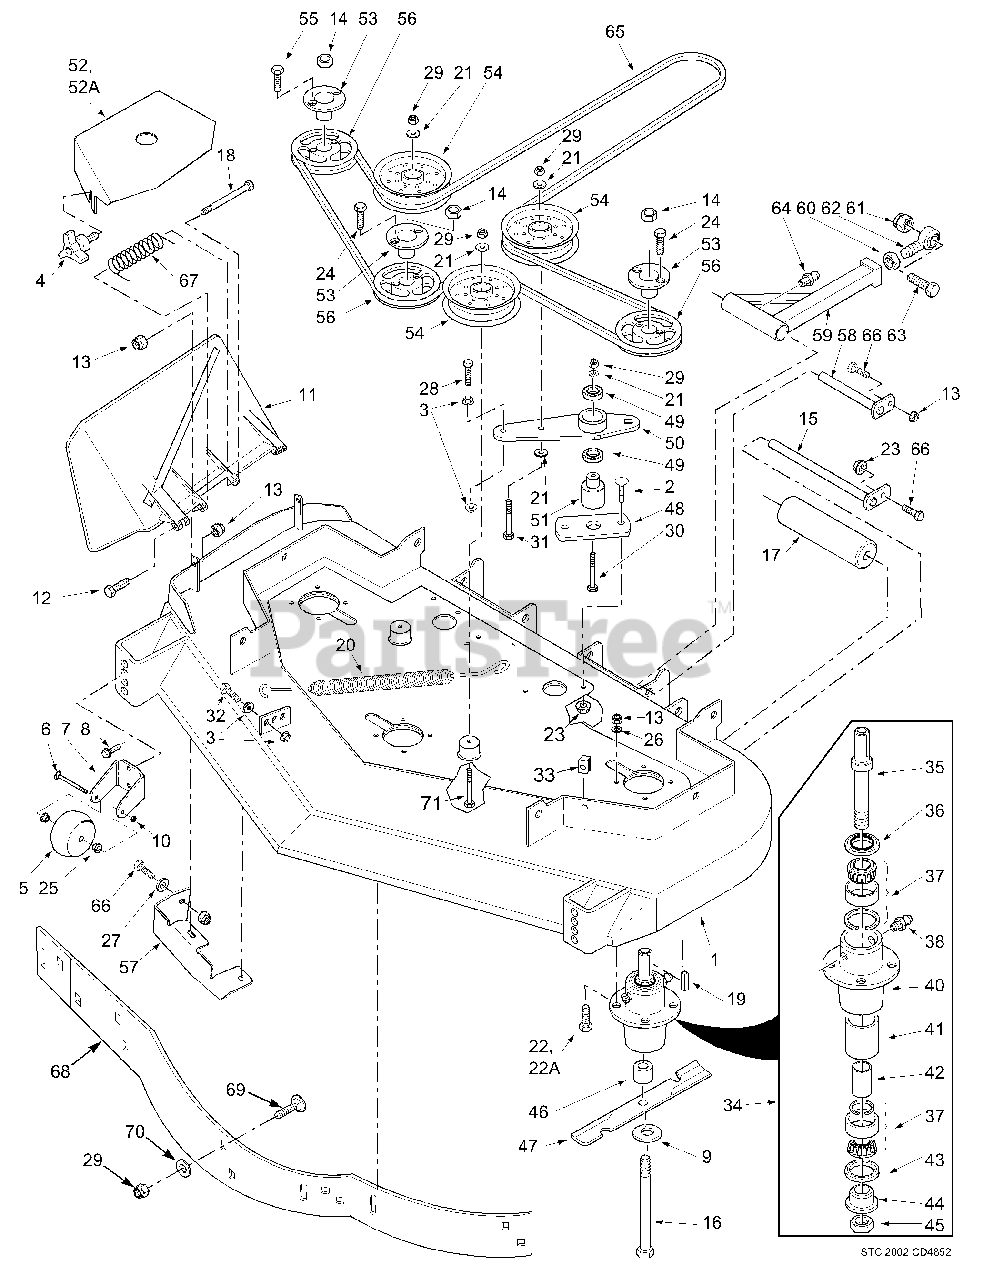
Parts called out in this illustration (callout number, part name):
1	Cutter Deck Advantage
2	Bolt, Carr. 5/16-18 x 1"
3	Nut, 3/8-16 Serrated Flange
4	Wing Nut, 3/8-16
5	Anti-Scalp Wheel
6	Bolt, Carriage 3/8-16 x 4"
7	Bracket, Anti-Scalp Wheel
8	Bolt, Serrated Flange 3/8-16 x 1"
9	Flatwasher, 5/8" Hardened
10	Locknut, 3/8-16 Center Lock
11	Discharge Chute
12	Bolt, Hex Head 5/16-18 x 1-1/2", Rear
13	Nut, Elastic Stop 5/16-18
14	Nut, 5/8-11 UNC
15	Shaft, Roller
16	Bolt, Hex Head 5/8-11 x 9-1/2"
17	Roller, Rear
18	Bolt, Hex Head 5/16-18 x 4-3/4"
19	Key, 1/4 x 1/4 x 2"
20	Spring, Idler
21	Flatwasher, 3/8"
22	Bolt, Hex Head 5/16-18 x 1-1/2"
22A	Bolt, Hex Head 5/16-18 x 1-3/4"
23	Nut, Serrated Flange 5/16-18
24	Bolt, Hex Head 1/2-20 x 3/4"
25	Bushing, .376 ID Oilite
26	Lockwasher 5/16"
27	Flatwasher 5/16"
28	Bolt, 3/8-16 x 1-1/2" Grade 8
29	Nut, Elastic Stop 3/8-16
30	Bolt, Hex Head 3/8-16 x 2-1/2"
31	Bolt, Hex Head 3/8-16 x 3.25"
32	Bolt, Hex Head 3/8-16 x 1-1/2 Grade 8
33	U-Nut, 3/8-16
34	Spindle Assembly
35	Shaft, Spindle
36	Seal Upper
37	Bearing Assembly
38	Grease Fitting
40	Housing, Spindle
41	Spacer, Outside
42	Spacer, Inside
43	Seal, Lower
44	Bushing, Bottom
45	Nut, Special 1-1/16 - 18
46	Spacer, Spindle
47	Cutter Blade 16.5"
48	Pivot, Idler Base
49	Bearing
50	Idler Arm Assy.
51	Idler Pivot
52	Belt Cover LH (48A)
52A	Belt Cover RH (48A)
53	Hub, Tapered 1-1/8" Bore
54	Pulley, Idler 5.0"
55	Bolt, Hex Head 1/4-20 x 1"
56	Pulley 4.75"
57	Turbo Baffle, Bolt On
58	Push Arm Shaft
59	Push Arm
60	Nut, 5/8-18 UNF
61	Nut, Elastic Stop 5/8-11
62	Rod End, 5/8 Male RH Thread
63	Bolt, Hex Head 5/8-11 x 4-1/2"
64	Grease Fitting, 90 Degree
65	Belt, Cutter Deck Drive (48A")
66	Bolt, Hex Head 5/16-18 x 1"
67	Spring, Discharge Chute
68	Baffle Weldment, 48A
69	Bolt, Carriage 3/8-16 x 1"
70	Flatwasher, 3/8-.391 x .938 x .105
71	Bolt, Hex Head 3/8-16 x 3-3/4"
